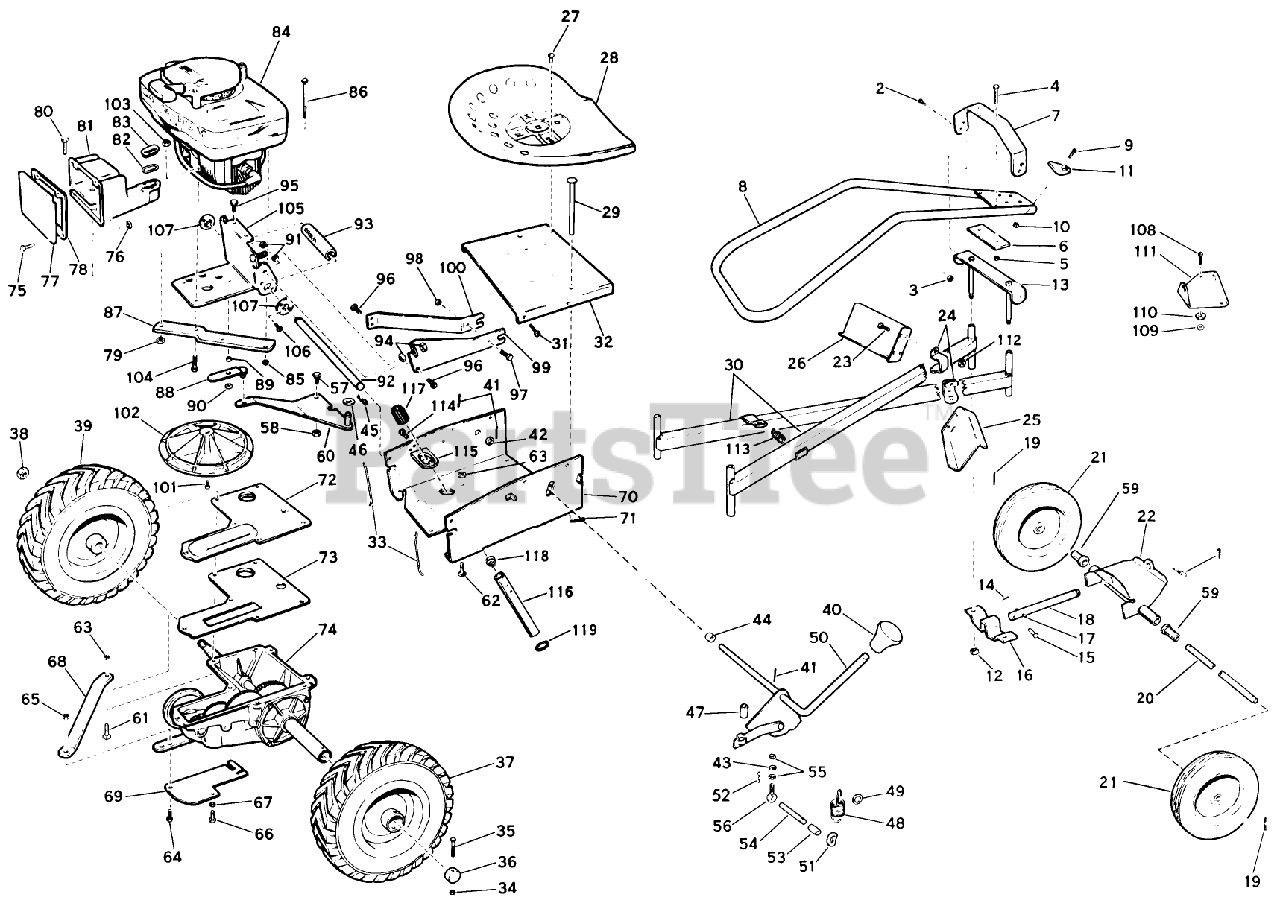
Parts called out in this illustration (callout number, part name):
2	Bolt-Handle
3	STOP NUT
10	STOP NUT
14	Cotter Pin
16	Pivot Bracket-Frame, Bottom
27	Screw-Seat to Cover
28	Seat Assembly
32	Cover-Shroud
35	Screw-Differential
43	WASHER, LOCK
44	Roller-Speed Control
48	Spring-Clutch
51	Clip-Clutch Spring
56	Bolt-Eye, Ramp Pin Adjustment
59	Bearing-Wheel, Nylon
61	Screw-Shroud
66	Screw-Guard to Housing
70	Shroud-Frame
74	Transmission Assembly
79	Nut-Huglok
85	LOCKNUT E
92	Shaft-Engine Mounting Plate
98	STOP NUT
99	Arm-Clutch
107	Bearing-Engine Mounting
109	STOP NUT
113	Spring-Clutch
119	Seal, Tube-Oil Filler
